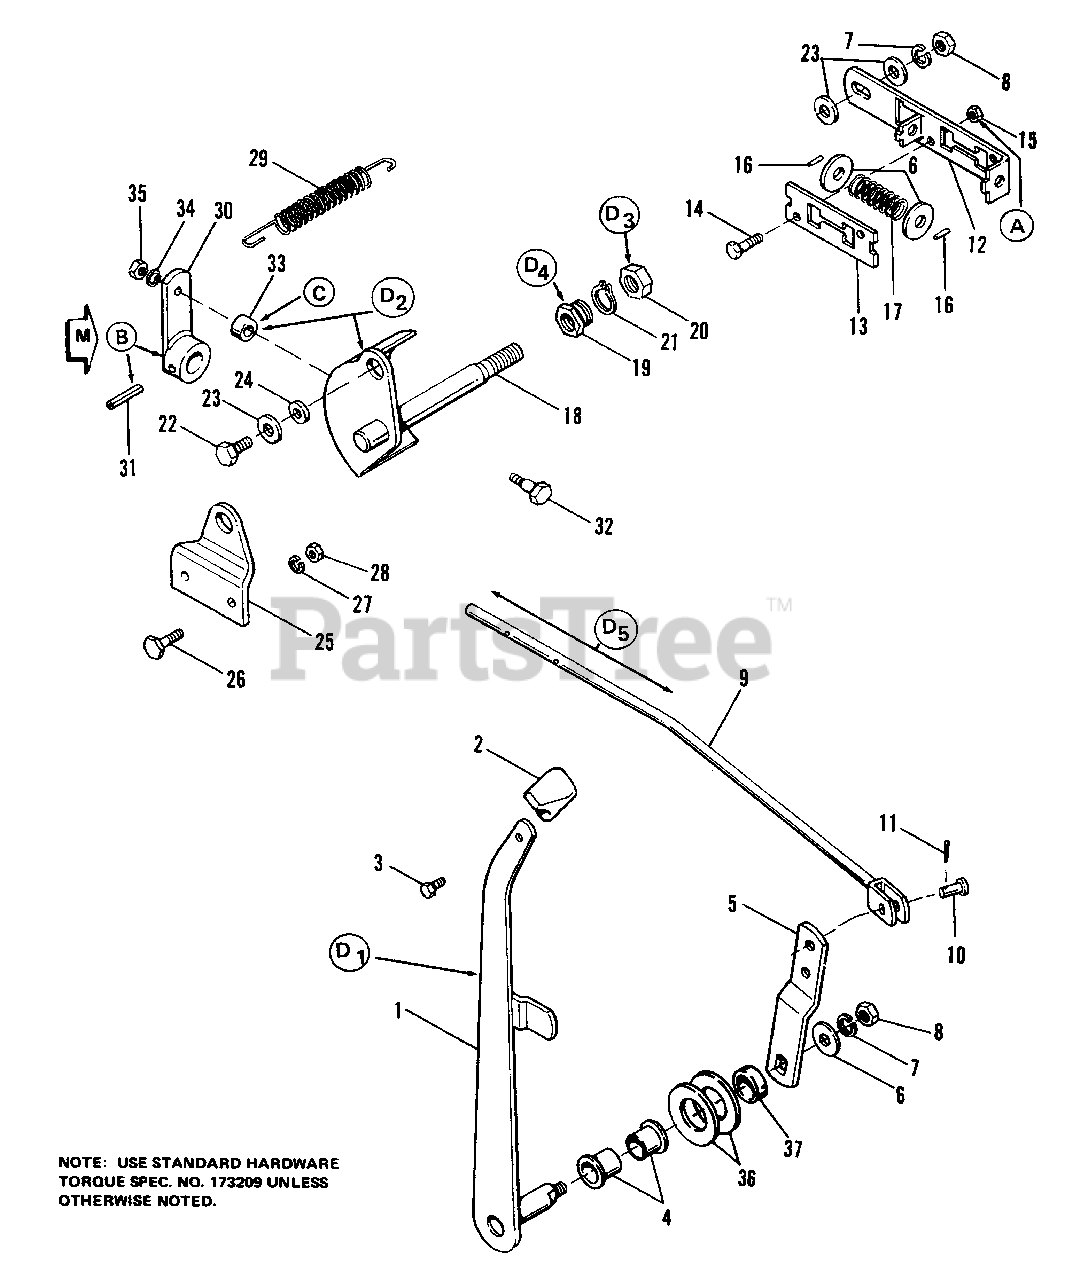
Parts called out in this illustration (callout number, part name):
1	LEVER ASSY, Control
3	SCREW, Thd. Form., 1/4-20 x 3/4
6	WASHER, 3/8
7	LOCKWASHER, 3/8
8	NUT, Hex, Full, 3/8-16
9	ROD ASSY, Control
11	PIN, Cotter, 3/32 x 3/4
12	GUIDE, Control Rod
13	PLATE, Guide
14	CAPSCREW, Hex Hd., 1/4-20 x 1-1/4
15	LOCKNUT, Hex, 1/4-20
19	NUT, Adjusting
20	NUT, Hex, Jam, 1/2-13
21	RING, Retaining
22	CAPSCREW, Hex Hd., 3/8-16 x 1
23	WASHER, 5/16
25	BRACKET, Pivot
26	SCREW, Special
27	LOCKWASHER, 5/16
28	NUT, Hex, Full, 5/16-18
30	LINK ASSY, Control
31	PIN, Roll, 1/4 x 1-1/4
32	BOLT, Shoulder
33	ROLLER, Cam
34	LOCKWASHER, 1/4
35	NUT, Hex, Full, 1/4-20
36	WASHER, Spring
